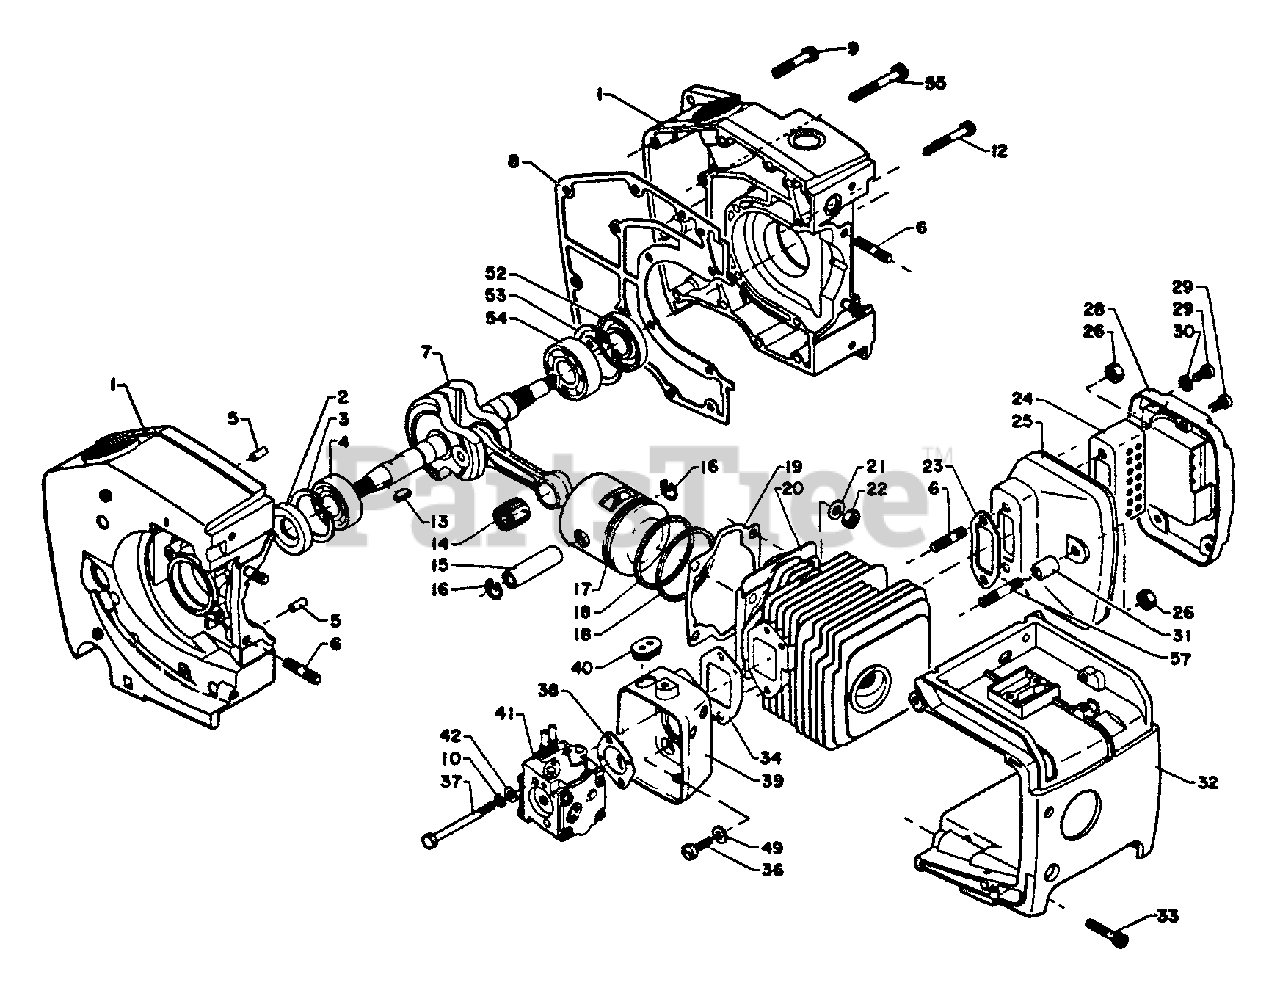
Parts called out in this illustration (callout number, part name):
1	CRANKCASE KIT
1A	CRANKCASE KIT
1B	CRANKCASE KIT
2	SEAL, OIL
3	RING, RETAINING - 35
4	BEARING, BALL - 6202
5	PIN - LOCATING
7	CRANKSHAFT ASSY
8	GASKET, CRANKCASE
9	SCREW - 5X30
10	LOCKWASHER - 5
12	SCREW - 5X35
13	KEY - 3X14
14	BEARING, NEEDLE
15	PIN, PISTON
16	RING, RETAINING
17	PISTON
18	RING, PISTON
19	GASKET, CYLINDER
20	CYLINDER
21	WASHER - 4
23	GASKET, EXHAUST
24	BAFFLE, MUFFLER
25	MUFFLER
26	LOCKNUT - 6
28	LID, MUFFLER
29	SCREW - 5X8
30	LOCKWASHER - 5
32	COVER, ENGINE
33	SCREW - 5X20
34	GASKET, INTAKE
37	BOLT
38	GASKET, INTAKE
39	CASE, CARBURETOR
40	GROMMET
41	CARBURETOR
42	WASHER - 5
52	SEAL, OIL
53	RING, RETAINING - 40
54	BEARING, BALL - 6203
55	SCREW - 5X40
57	STUD
